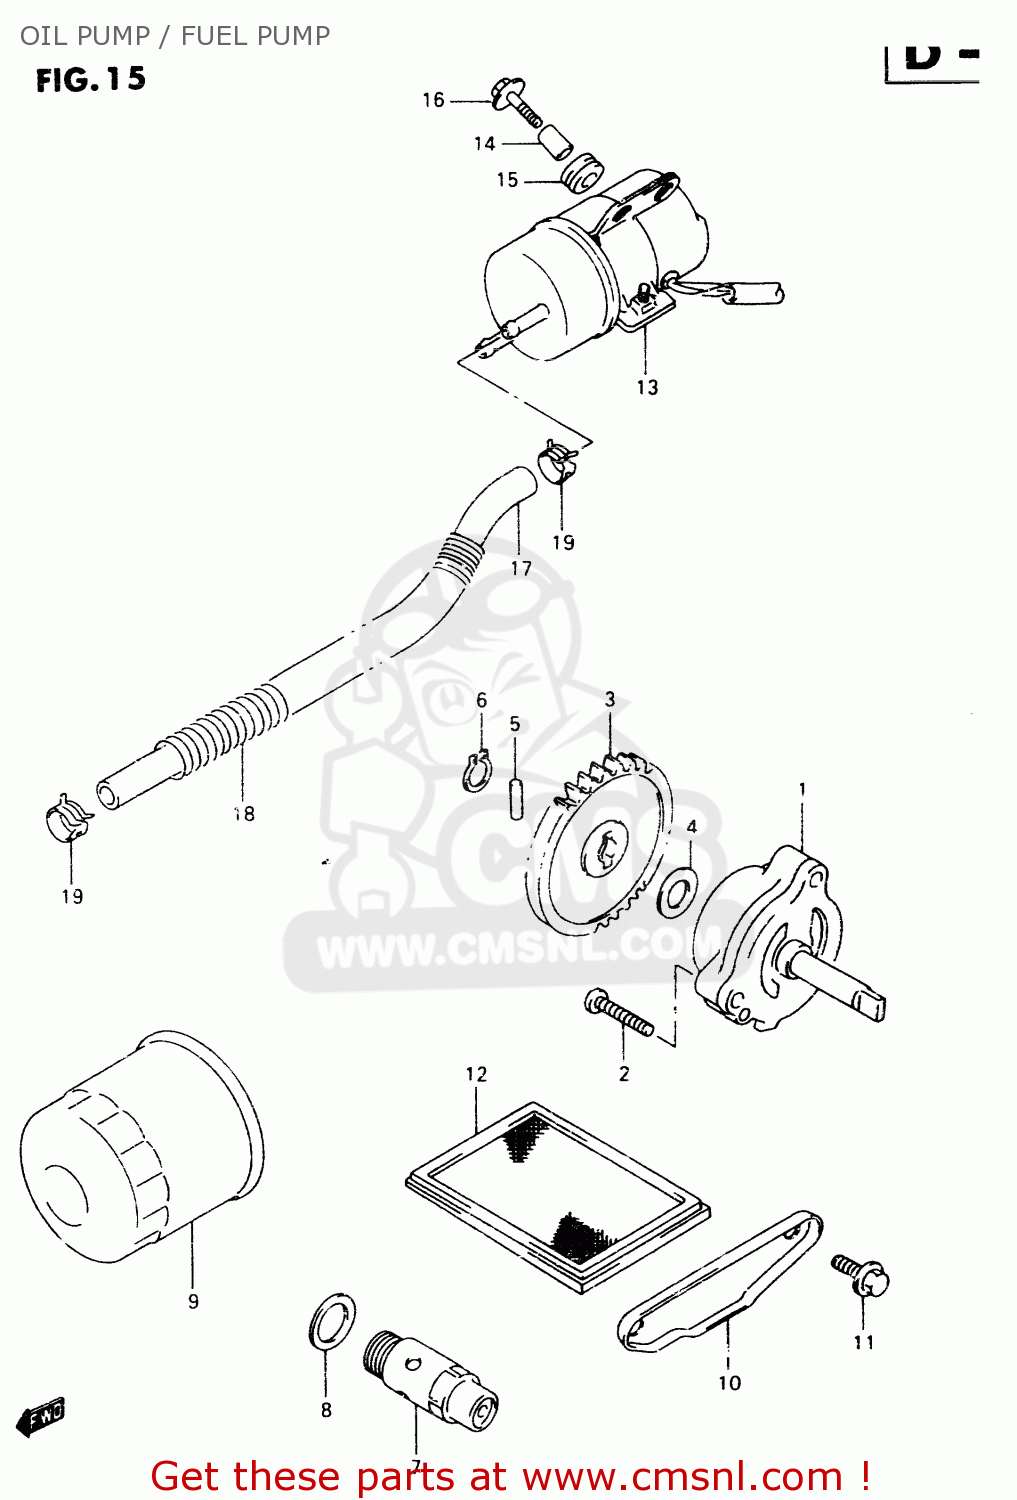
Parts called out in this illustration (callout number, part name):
1	PUMP ASSY,ENGINE OIL
2	SCREW
3	GEAR,OIL PUMP DRIVEN(NT:34)
4	SHIM(10X18X0.5)
5	PIN(4X15.8)
6	CIRCLIP,10MM
7	VALVE ASSY,OIL RELIEF
8	GASKET(16X22X2) (NAS)
9	FILTER ASSEMBLY,ENGINE OIL
10	CAP,OIL STRAINER
11	BOLT 6X12
12	STRAINER,ENGINE OIL
13	PUMP ASSY,FUEL
14	SPACER(6.5X9X9)
15	CUSHION
16	BOLT 6X20
17	HOSE(7X12X600)
18	SPRING
19	CLIP
